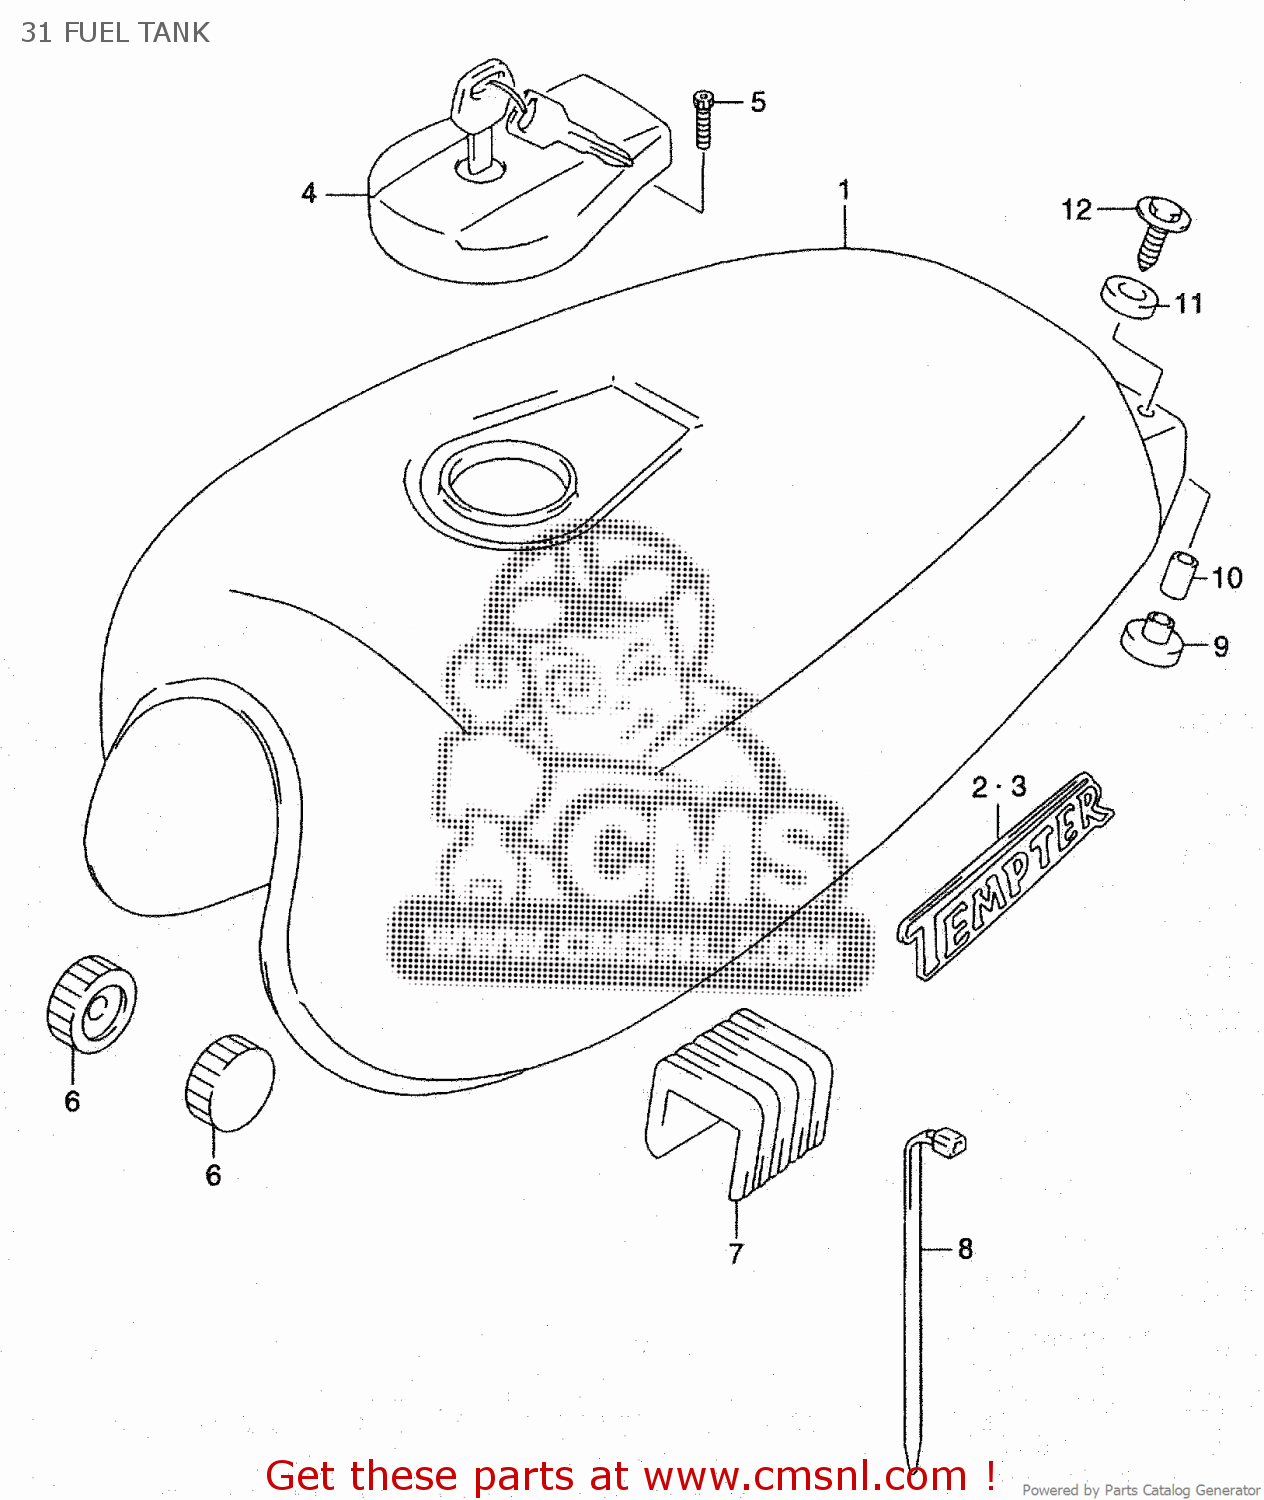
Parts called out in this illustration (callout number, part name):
5	BOLT
6	CUSHION
7	CUSHION
8	CLAMP(L:250)
9	CUSHION
10	SPACER(6.5X9X18)
11	CUSHION,FUEL TANK RR
12	BOLT(6X30)
